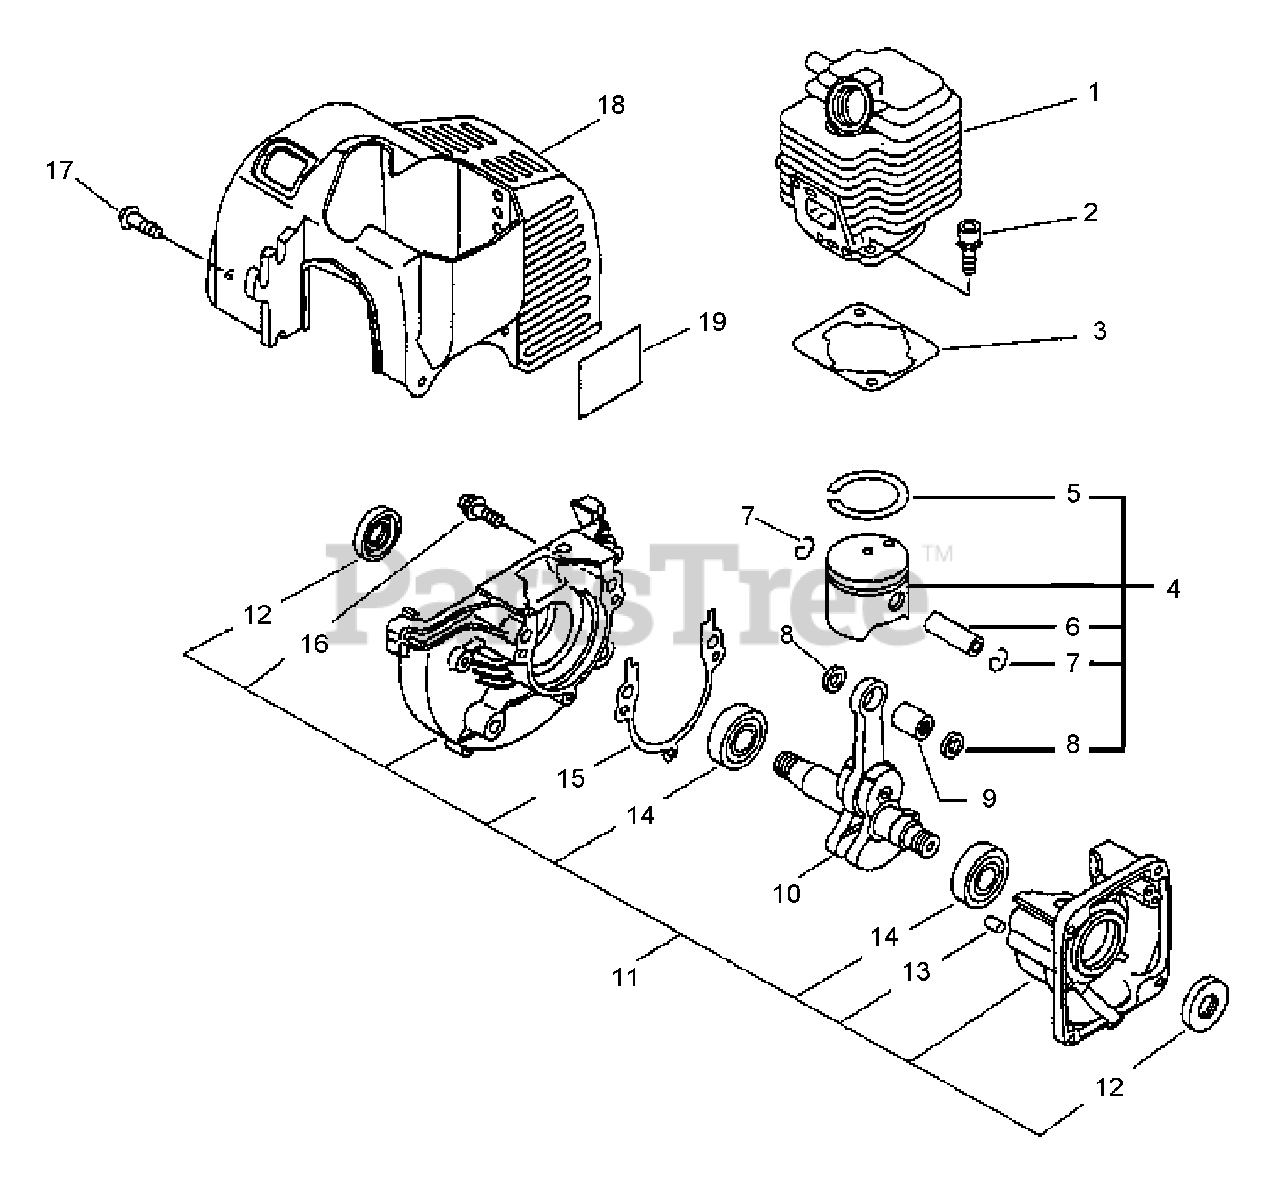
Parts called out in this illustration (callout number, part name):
1	CYLINDER
2	SCREW - 5X22
3	GASKET, CYLINDER
4	PISTON KIT
5	RING, PISTON
6	PIN, PISTON
7	RING, RETAINING
8	SPACER, PISTON
9	BEARING, NEEDLE
10	CRANKSHAFT ASSY
11	CRANKCASE KIT
12	SEAL, OIL
13	PIN - LOCATING
14	BEARING, BALL - 6201
15	GASKET, CRANKCASE
16	SCREW - 5X28
17	SCREW - 4X16
18	COVER, ENGINE - ORANGE
18	COVER, ENGINE - GRAY
19	LABEL - MODEL
